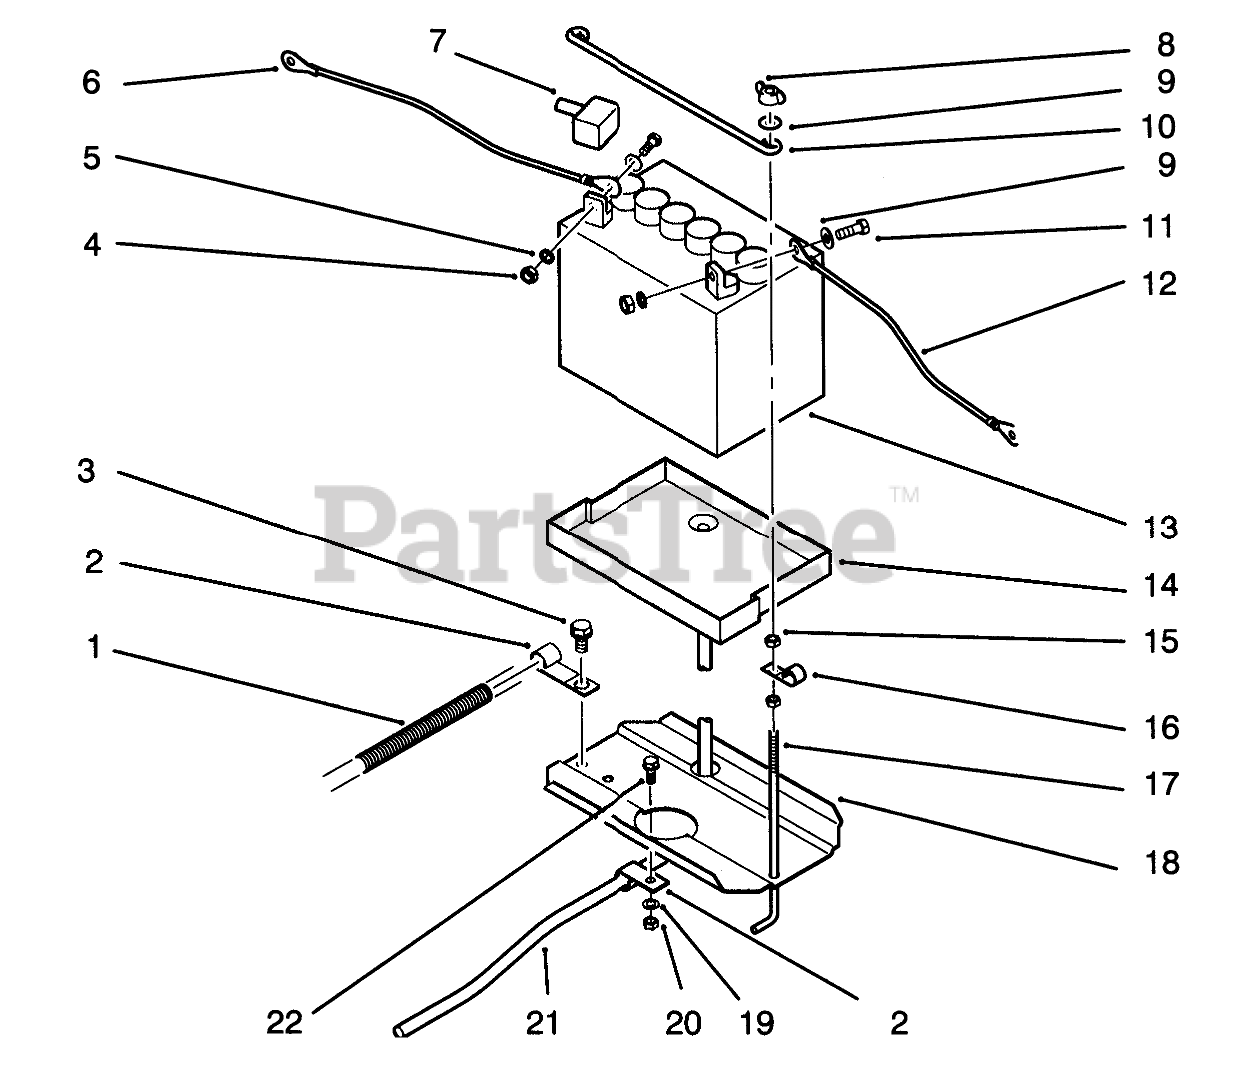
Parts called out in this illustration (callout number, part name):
1	WIRING-HARNESS & DIA
2	CLIP
3	Screw
4	NUT-HEX
5	WASHER-LOCK
6	WIRE - 14" BLACK
7	Boot
8	NUT-WING
9	WASHER-FLAT
10	ROD-BATTERY HOLD DWN
11	SCREW-HH
12	ASS'Y-WIRE
13	Battery
14	TRAY-BATTERY
15	NUT-HEX
16	CLAMP
18	Tray
19	WASHER-FLAT
20	NUT-LOCK, NI
21	TUBE-21" BATTERY DRAIN
22	Screw
